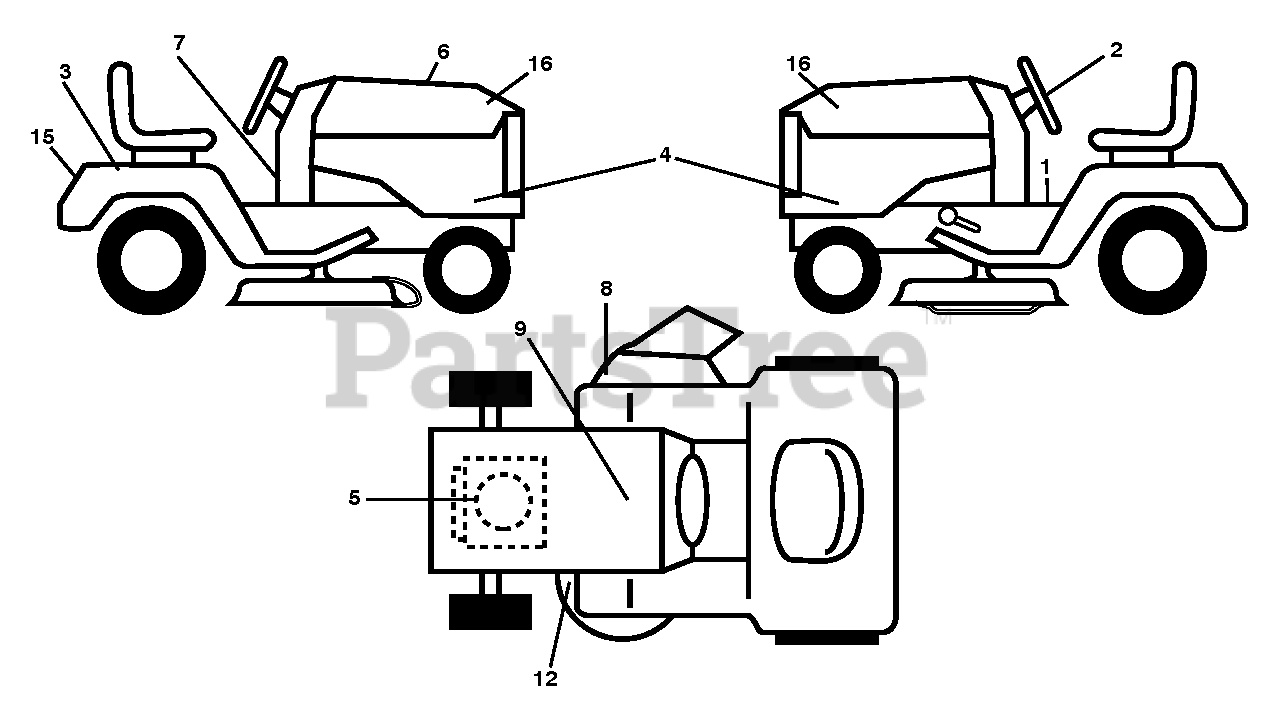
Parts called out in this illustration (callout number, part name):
1	Fender Engine Warning Decal
3	DECAL SERVICE
8	DECAL.WARN.KEEP.HAND.AWAY
9	DECAL BTRY SYMBOLS
